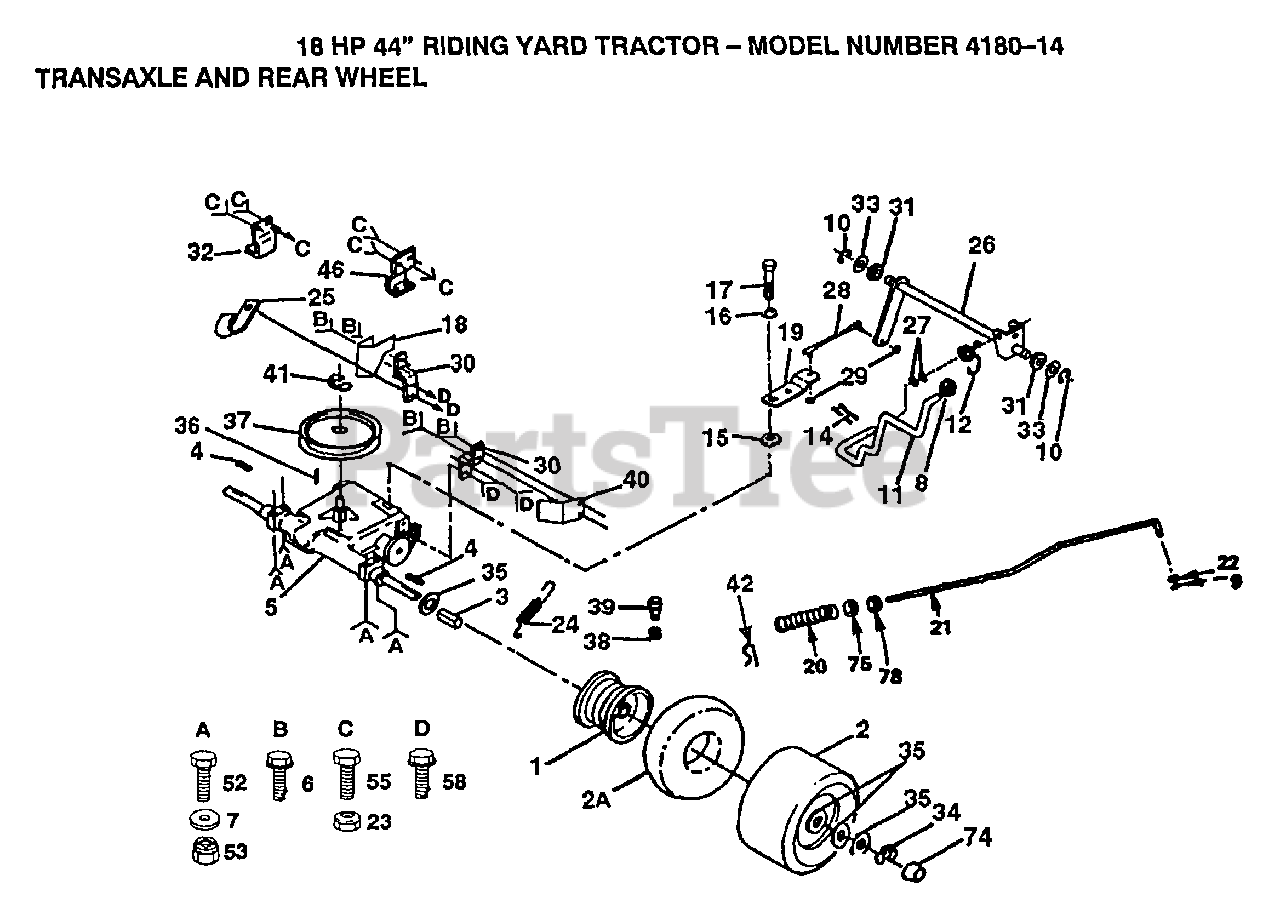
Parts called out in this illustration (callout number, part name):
2A	TUBE.23X8/10-12
3	SPACER HYT
4	SQ KEY STD
5	TRANSAXLE PEERLESS MODEL NO
6	SCREW
7	WASHER
8	KNOB T (1/2-HOLE)
9	COTTER PIN
10	KLIP RING
12	"SPRING,TORSION"
14	PIN COTTER 1/8
15	WASH-SHFT PLT LT
16	WASHER PM
18	KEEPER BELT LH
19	"ARM,SHIFT"
20	"SPRING,ROD BRAKE"
21	ROD BRAKE
22	WASHER
25	CLIP T
26	"SHAFT,SHIFTER"
27	WASHER
28	"ROD,TIE "
29	NUT 1/4-28
30	STRAP TORQUE
31	BUSHING
32	BRKT TRANS LH
33	WASHER D
34	E RING HYT
35	WASHER
37	PULLEY TRANSAXLE
38	VALVE CAP
39	VALVE STEM LT
40	"KEEPER,BELT RH"
41	RING
42	RETAINER M
46	BRKT TRANS RH
52	BOLT HEX
58	SCREW
74	HUB CAP
75	NUT
78	NUT
